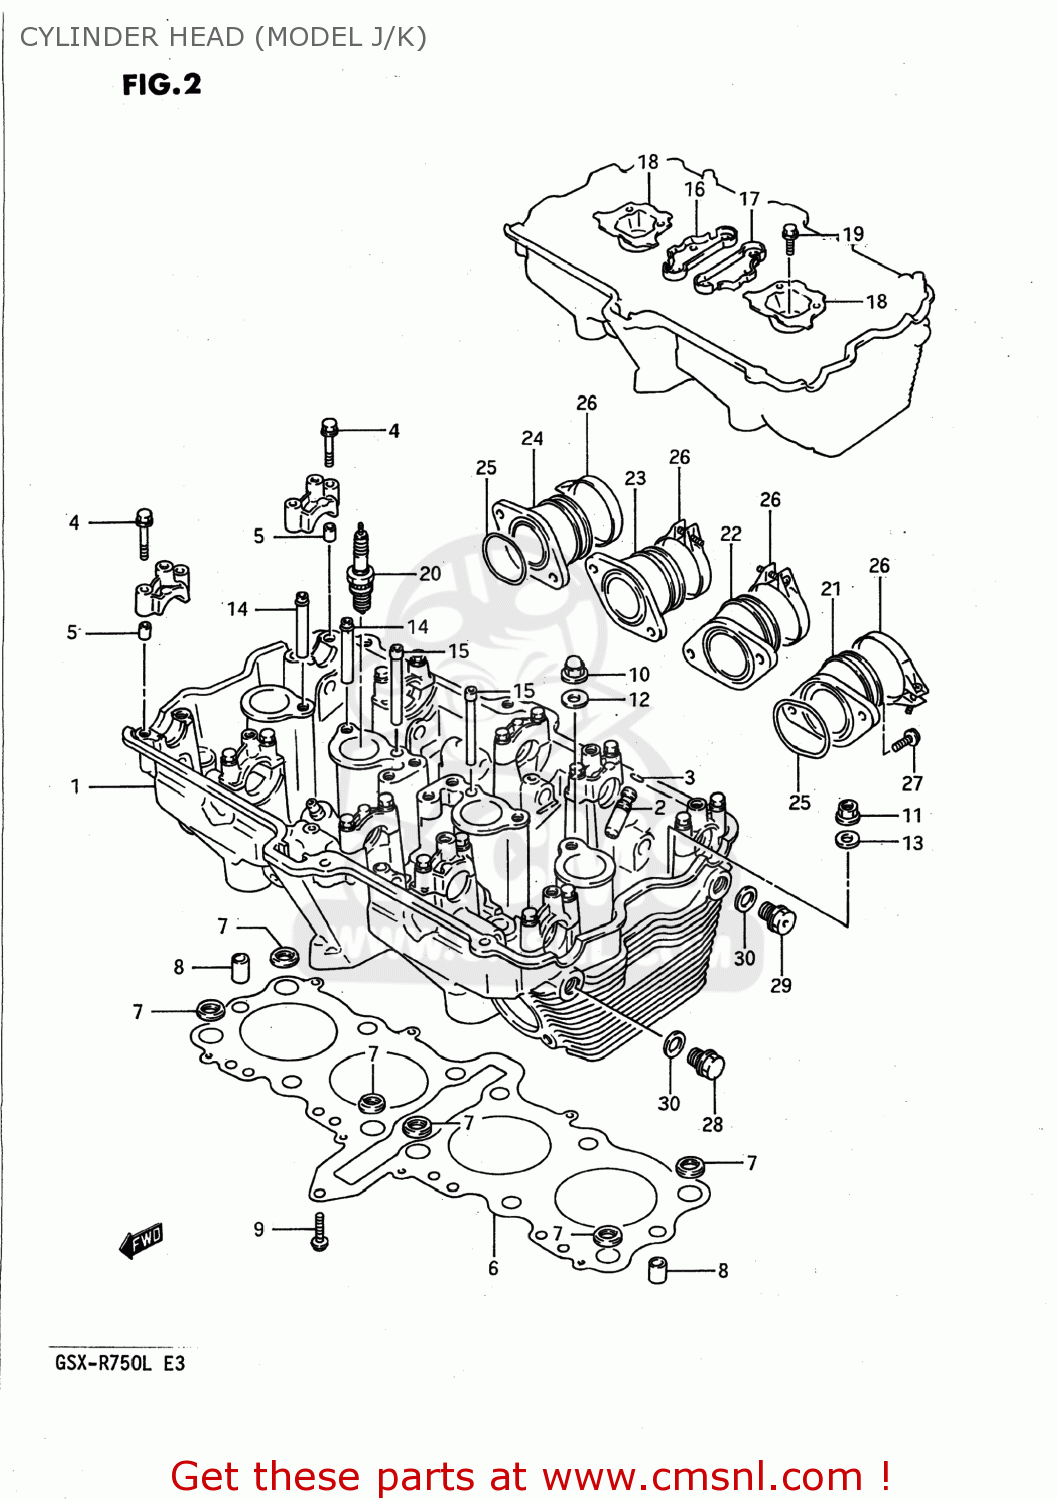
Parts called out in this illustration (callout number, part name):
1	HEAD ASSEMBLY,CYLINDER
2	GUIDE,VALVE
3	RING,SNAP
4	BOLT(6X39)
5	PIN(6.2X8X11)
6	GASKET,CYLINDER HEAD
7	O RING,HEAD GASKET
8	PIN
9	BOLT
10	NUT
11	NUT
12	GASKET(10.2X20X2).3 (NAS)
13	WASHER (10.5X22X2.3)
14	PIPE,OIL NO.1
15	PIPE,OIL NO.3
16	PLATE
17	PLATE
18	PLATE
19	BOLT
20	PLUG,SPARK(JR9C)
21	PIPE,INTAKE
22	PIPE,INTAKE
23	NET,INTAKE
24	PIPE,INTAKE
25	O RING(D:2.4,ID:39.7)
26	CLAMP
27	SCREW
28	PLUG
29	PLUG
30	GASKET(14X19.2X2) (NAS)
